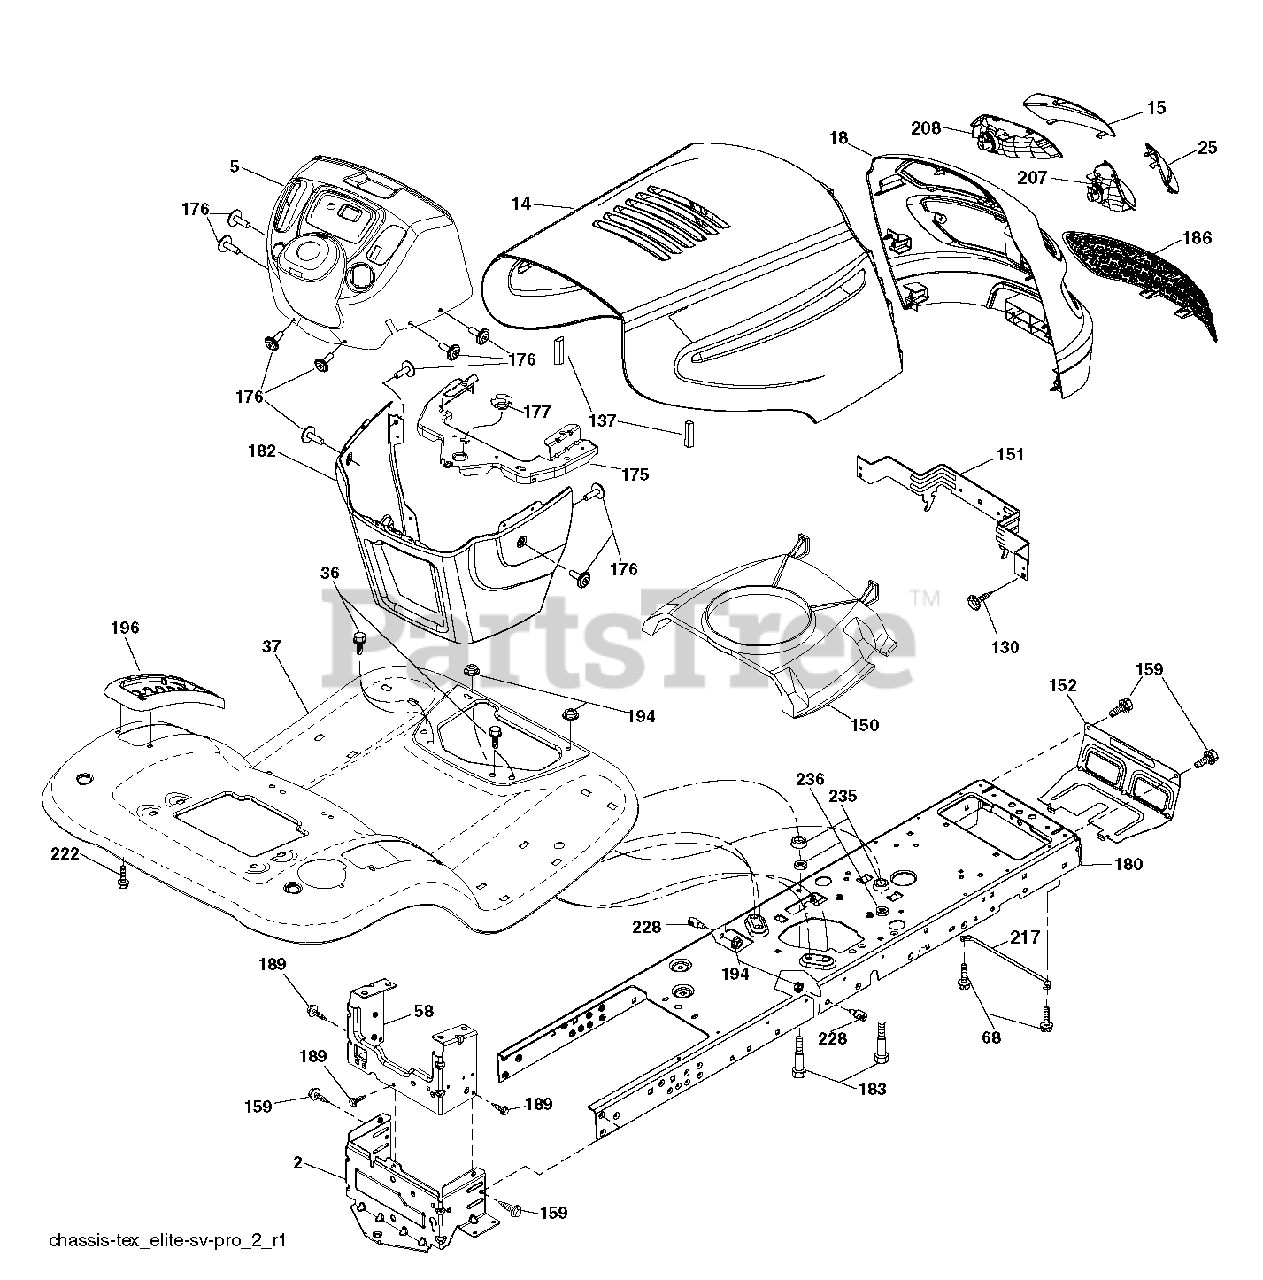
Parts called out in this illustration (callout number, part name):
2	DRAWBAR.LOWER.2PC.18/22
36	SCREW 5/16"
130	SCREW
137	BUMPER.HOOD.LARGE.1.75"
151	BRACKET PIVOT
152	SHIELD.BROWNING/DEBRIS
159	SCREW, 3/8-16X3/4
175	CROSSMEMBER.LT
176	SCREW.#10-24X5/8.RN.QU
177	BUSHING STEERING
180	CHASSIS.STAMPING.LT/GT
182	DASH.LOWER.LT.CCS
183	BOLT.5/16-18X1-1/4 FULL.THREAD
189	SCREW
194	NUT LOCK HEX FLANGE 5/16-18
196	CONSOLE.ASM.DECK.LIFT.TLT.BLAC
207	BEZEL GRILL RH
208	BEZEL GRILL LH
217	ROD.PIVOT.HOOD
222	SCREW.1/4-20X5/8
228	STUD.FASTNER.W/ANTI-ROTATE
235	SPACER FENDER
236	NUT.CENTERLOCK.5/16-
